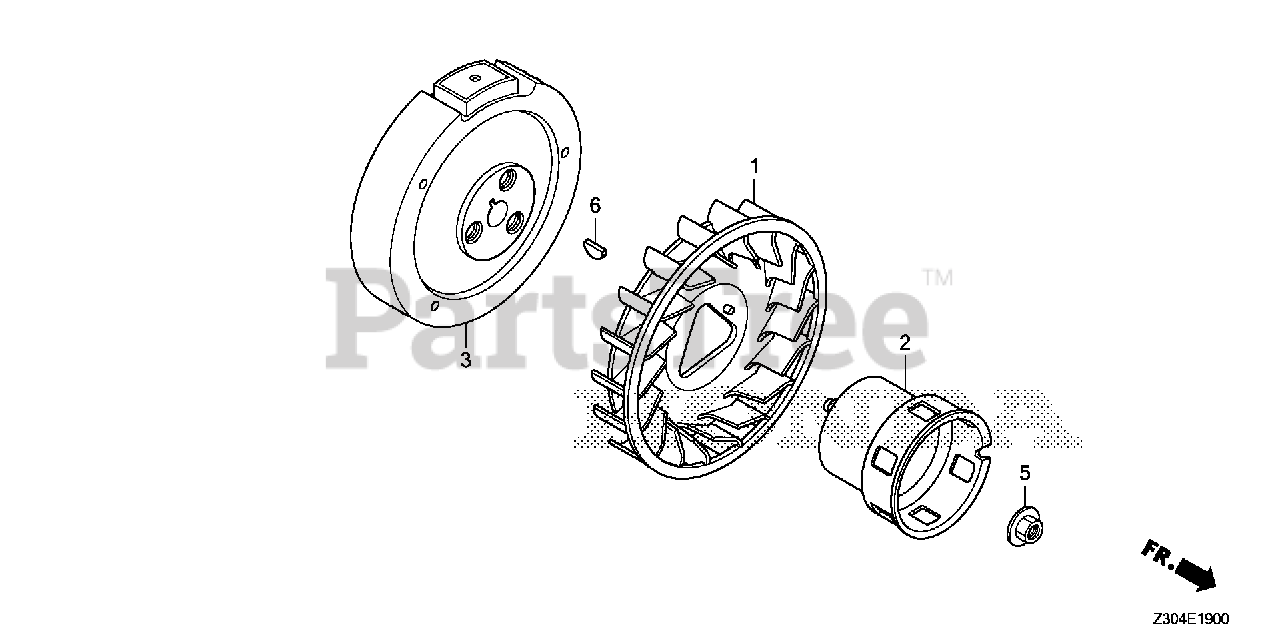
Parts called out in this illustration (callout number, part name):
1	FAN, COOLING
2	PULLEY, STARTER
3	FLYWHEEL (LAMP)
5	NUT, SPECIAL (16MM)
6	KEY, SPECIAL WOODRUFF (25X18)
